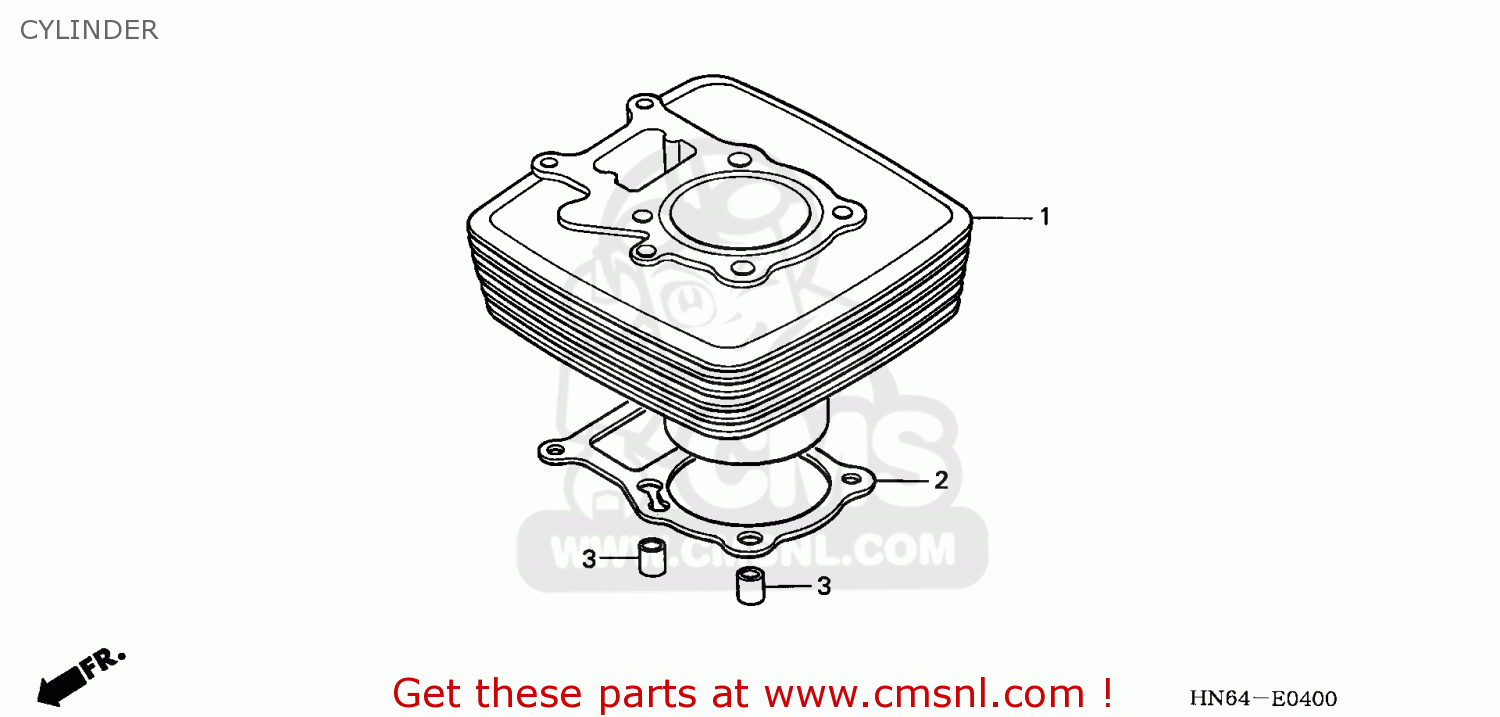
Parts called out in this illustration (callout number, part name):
1	CYLINDER COMP
2	GASKET,CYLINDER (NAS)
3	PIN,DOWEL,10X14
